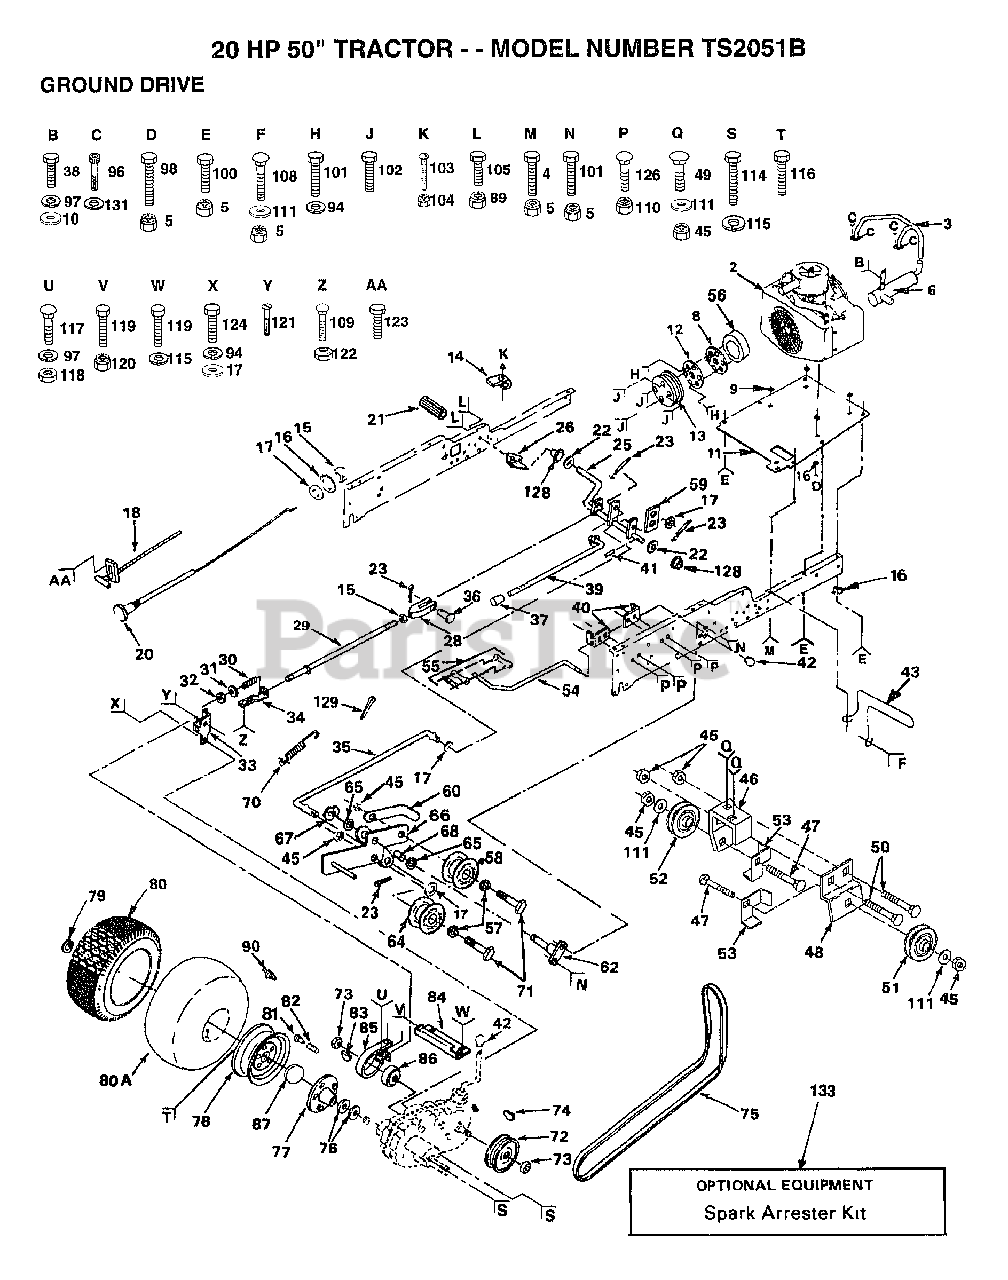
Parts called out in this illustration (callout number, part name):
3	EXHAUST TUBE T
4	"BOLT,HEX"
5	NUT
6	MUFFLER EXHAUST
8	CHAFF GUARD T
9	SPACER.ENGINE KOH
11	"ENG. T, BASE"
12	ADAPTER T
14	ACT-SWITCH T
16	LOCKWASHER
17	WASHER
21	PEDAL COVER T
22	WASHER
25	SHAFT ASSY GT
26	BRKT SWITCH GT
28	YOKE GTV
29	BRAKE ROD T
30	SPRING T
31	WASHER
33	BRAKE BRKT ASSY T
34	GUIDE ROD T
35	ROD CLUTCH GTV
36	CLEVIS PIN T
37	PLUNGER CAP T
39	BRAKE ROD
40	ROD BRACKET GT
41	ROLL PIN STD
42	KNOB
43	GUARD MUFFLER HYT
46	BRACKET V IDL DRV
47	BOLT
48	BRACKET IDLER FLT
49	BOLT
51	IDLER-FLAT T
52	PULLEY V IDLR GTV
53	GUARD BELT
54	ROD SHIFT HI LO
55	CONNECTING LINK
57	WASHER
59	RETAINER SPRING
60	RETAINER BELT
62	BRACKET ASSY GTV
65	WASHER T
66	BRACKET CLUTCH
67	KLIP RING
68	"LY, BEARING"
70	SPRING EXT CLUTCH
73	NUT STD
75	BELT-V.98.5.GD.DV
76	WASHER T
79	KLIP RING
80A	TUBE.23X8/10-12
81	VALVE CAP
82	VALVE STEM LT
85	BRAKE BAND ASM
86	BRAKE DRUM T
87	"COVER, HUB"
89	NUT
90	ZERK FITTING M
94	LOCKWASHER
96	SCREW
97	LOCKWASHER
100	BOLT
101	BOLT
102	SCREW
103	SCREW
105	BOLT LT
108	BOLT D
110	NUT
111	WASHER GT
114	BOLT
115	LOCKWASHER
116	BOLT.HUB.WHL.REAR
117	BOLT T
119	BOLT
120	NUT GTV
121	SCREW
123	SCREW LT
126	BOLT
128	NYLINER T
129	COTTER PIN
133	SPARK ARREST KIT
